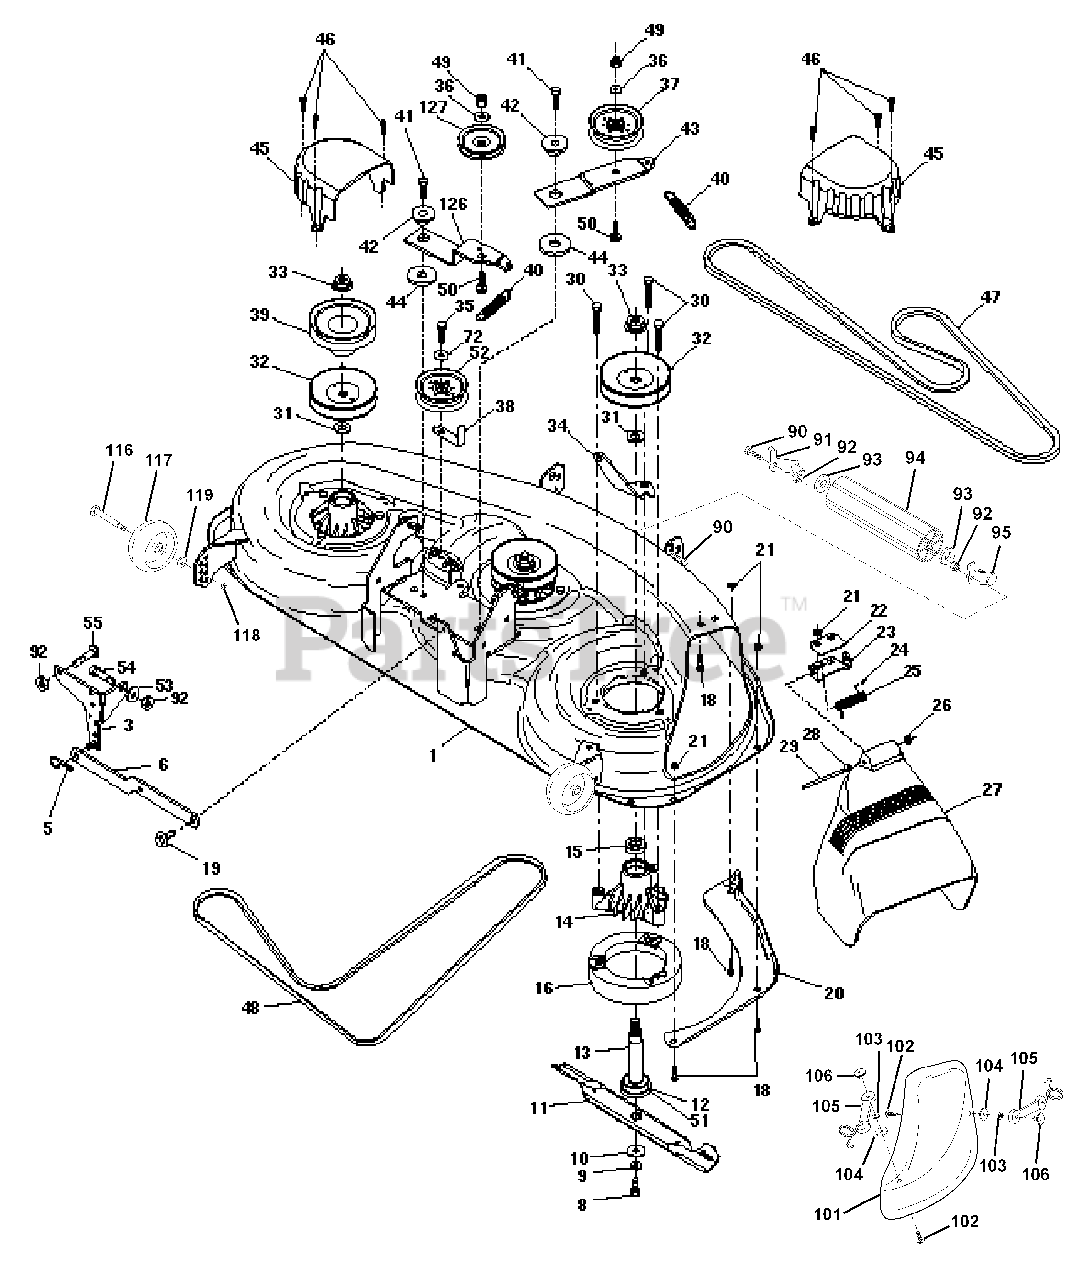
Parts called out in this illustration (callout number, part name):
1	Deck Asm., Mower 46"
3	Bracket Asm., Sway Bar
5	Retainer Spring
6	Arm, Suspension, Rear
8	Bolt, Patched 3/8-24 x 1-1/4 Gr. 8
9	Washer, Lock Hvy., Unplated 3/8
10	Washer, Hard Blade, Mower Vented
11	Blade, 46" Mower Deck
12	Bearing, Ball, Mandrel #6204
13	Shaft Asm. w/Lower Bearing
14	Housing, Mandrel
15	Bearing, Ball, Mandrel
16	Stripper, Mower Round
18	Bolt, Carriage 5/16-18 x 5/8
19	Bolt, Hex Head, Shoulder 5/16-18
20	Baffle, Vortex Mower 46"
21	Nut, Crownlock 5/16-18 UNC
22	Stiffener, Bracket
23	Bracket, Deflector
24	Cap, Sleeve
25	Spring, Torsion, Deflector
27	Shield, Deflector Mower
28	Washer 11/32 x 5/8 x 16 Ga.
29	Rod, Hinge
30	Screw, Thdroll, Washer Head
31	Washer, Spacer Mower Vented
32	Pulley, Mandrel
33	Nut, Flg. Top Lock Cntr. 9/16
34	Anchor, Spring Deck 46"
35	Screw, Thdroll 3/8-16 x 1-3/4 Tytt
36	Washer 13/32 x 13/16 x 16 Ga.
37	Pulley, Idler, Flat
38	Keeper, Belt, Idler
39	Pulley, Idler, Driven
40	Spring, Secondary 44/46/50 Vent
41	Screw, Thdroll 3/8-16 x 1-1/4 Tytt
42	Spacer, Retainer
43	Arm, Idler Secondary
44	Washer, Hardened
45	Cover, Mandrel Deck
46	Screw, Thdroll. 1/4-20 x 5/8
47	V-Belt, Mower, Secondary
48	V-Belt, Mower, Primary
49	Nut, Crownlock 3/8-16 UNC
50	Bolt, Carriage 3/8-16 x 1-1/2 Gr. 5
51	Washer, Felt
52	Pulley Idler Flat 46 Pri. Drive
53	Washer 13/32 x 13/16 x 12 Ga.
54	Bolt Fin Hex 3/8-16unc x 1 Gr. 5
55	Bolt Rdhd Sqnk 3/8-16unc x 1
72	Washer 13/32 x 1 x 16 Ga.
90	Bolt, Fin, Hex 3/8-16 UNC x 1
91	Bracket, Asm Noseroller, LH
92	Nut, Lock, Hex w/Ins 3/8-16UNC
93	Washer 17/32 x 7/8 x 16 Ga.
94	Roller, Nose 38 & 42
95	Bracket, asm Noseroller RH
101	Cover, Mulching
102	Screw
103	Washer, Lock #10
105	Latch Asm. Bagger
106	Nut, Weld
116	Bolt, Shoulder
117	Gauge Wheel
118	Nut, Centerlock 3/8-16 UNC
119	Washer 3/8 x 7/8 x 14 Ga.
126	Arm, Idler, Primary Deck 46"
127	Pulley, Idler, V-Groove Dim. 4.25
127	Mandrel Assembly
127	Mower Serv 46"
